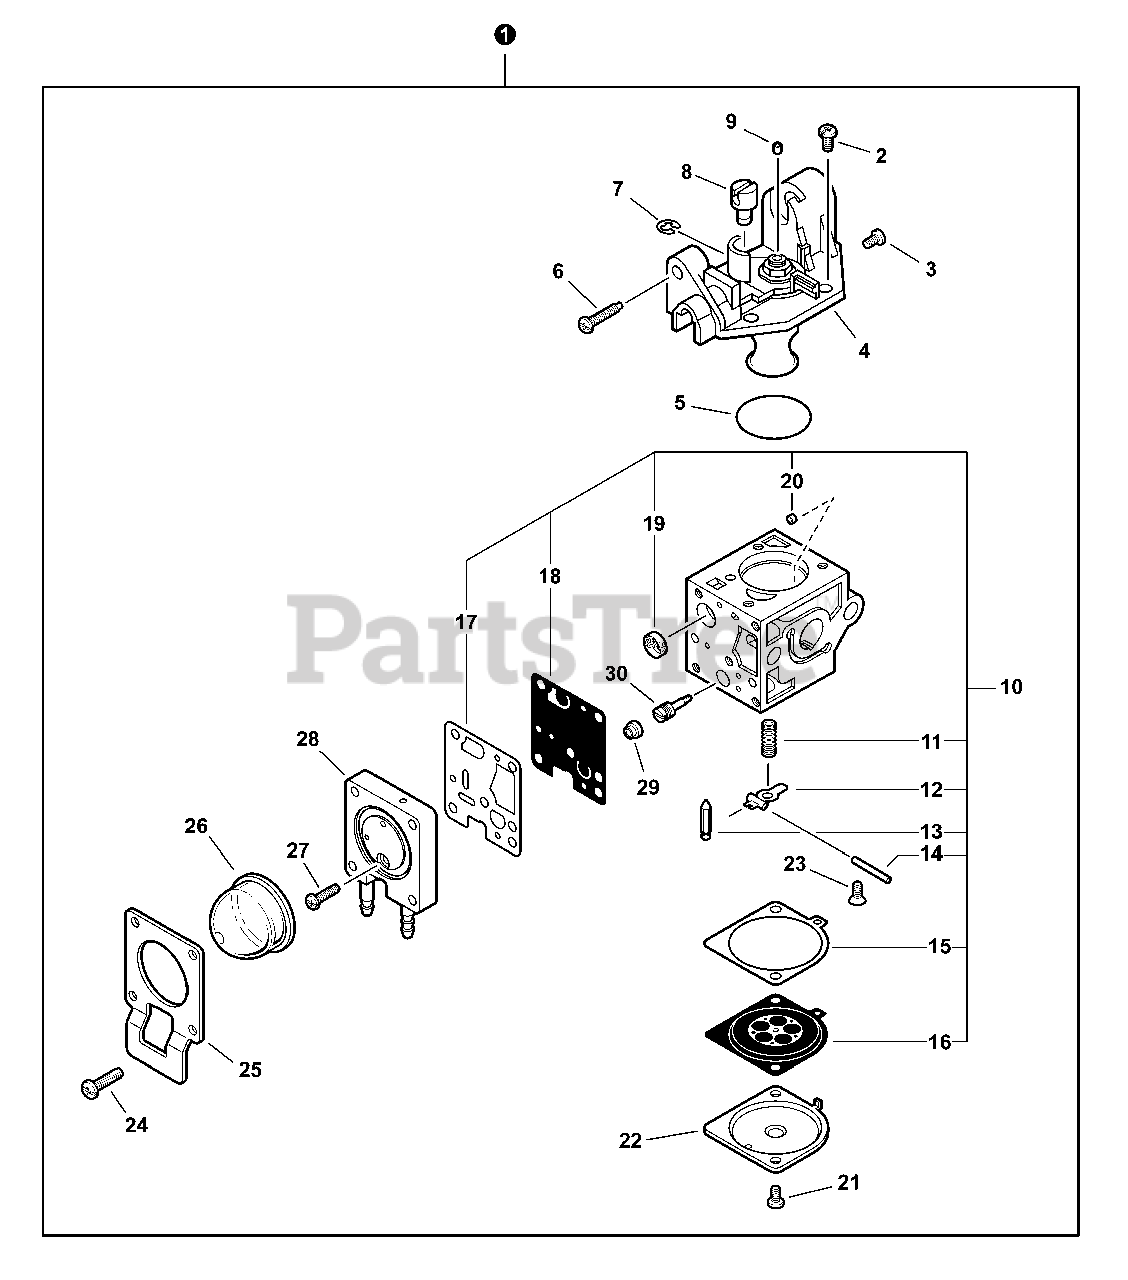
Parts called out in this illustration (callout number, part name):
1	CARBURETOR -- RB-K91A
4	ROTOR COVER ASSY
6	SCREW, IDLE ADJUST
7	RING, RETAINING
10	REPAIR KIT
11	SPRING, METERING LEVER
12	LEVER, METERING
13	VALVE, INLET NEEDLE
14	PIN, METERING LEVER
15	GASKET, DIAPHRAGM
16	DIAPHRAGM, METERING
17	GASKET, PUMP
18	DIAPHRAGM, PUMP
19	STRAINER
20	GUIDE, ROLLER
22	COVER, METERING
23	SCREW, METERING LEVER PIN
24	SCREW, PURGE BULB RETAINER
25	RETAINER, PURGE BULB
26	BULB, PURGE
27	SCREW, PURGE BASE
28	BASE, PURGE
30	NEEDLE - HIGH SPEED
